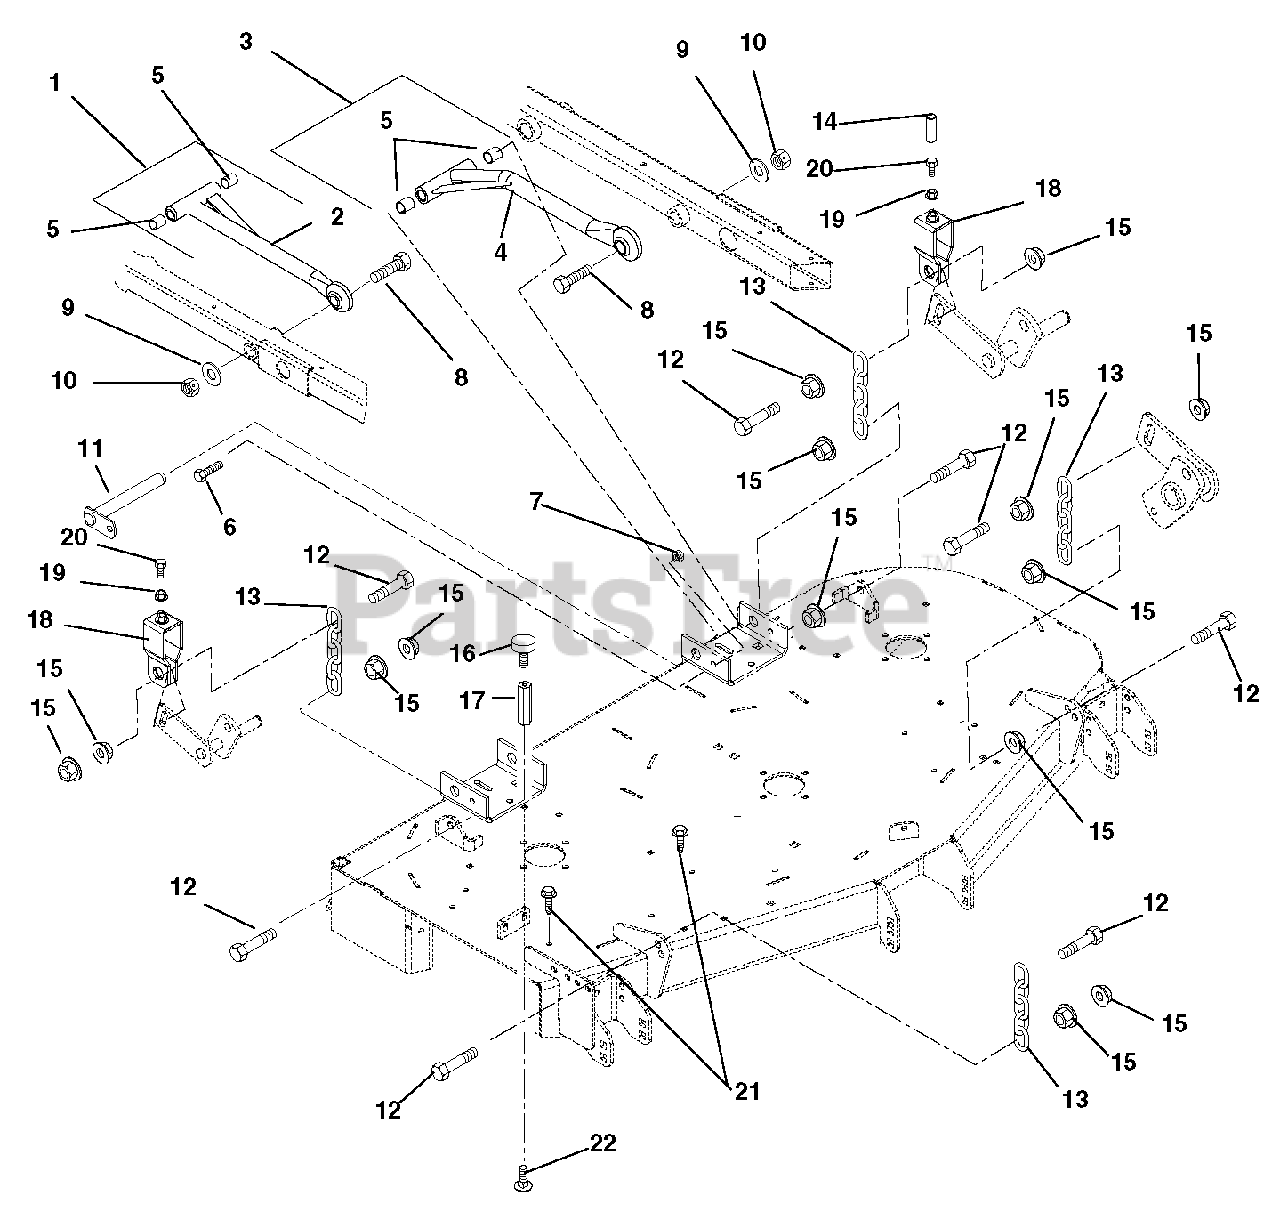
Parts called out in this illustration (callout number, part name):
1	Assembly, Mower Mounting Arm (Contains Items 2, 5)
2	Weldment, Mower Mounting Arm
3	Assembly, Mower Mounting Arm Left Hand (Contains Items 4,5)
4	Weldment, Mower Mount Arm
5	Bearing .75 x .875 x 1.00
6	Bolt, Hex .38-16 x .75 Grade 5
7	Nut, .38-16 Nyloc Flange
8	Bolt, Hex .875 x 5.50 Grade 5
9	Washer, Flat-Steel .875 x 1.500 x .1196
10	Nut, Locking-Center .875-9
11	Weldment, Mower Mounting Pin
12	Bolt, Hex M12-1.75 x 50 Grade 5
13	Chain, Link
14	Cap, Vinyl .50 ID x 1.50LG x .055
15	Nut, Spin Lock-Flange M12-1.75
16	Bumper, Rubber
17	Nut, Coupling .31-18 x 3.00
18	Bracket, Deck Leveling
19	Nut, Jam .312-18
20	Bolt, Full Thread Hex .312-18 x 2.00
21	Screw, Tapping Hex Washer Head Thread .38-16 x .50
22	Bolt, Round Head Square Neck .31-18 x .75
